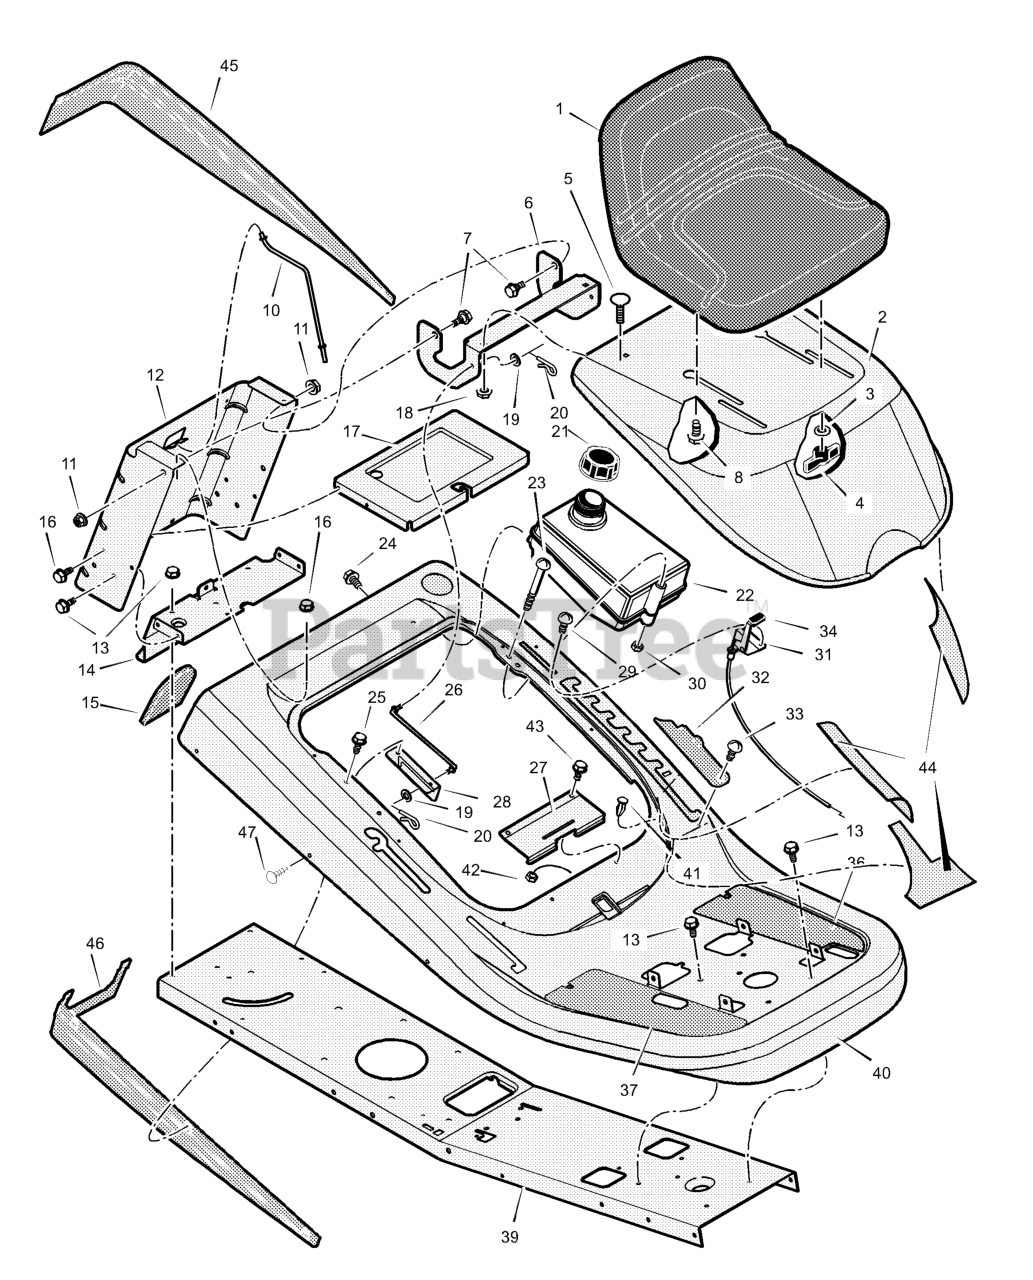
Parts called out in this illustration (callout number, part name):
3	Washer
4	Bolt, Wing
5	Bolt, Carriage
6	Bracket, Hinge
7	Bolt, Shoulder
8	Bolt, Shoulder
10	Rod, Battery
11	Nut, Flange
12	Plate, Rear
14	Plate, Hitch
17	TRAY, Battery
18	Nut, Flange
19	Washer
20	Pin, Cotter
21	Cap, Fuel Tank
22	Tank, Fuel
23	Screw
26	Rod, Hood Prop
27	Spring, Seat Deck
28	Bracket, Prop Rod
30	Nut, NY-Lock
31	Control, Throttle
32	Cover, Detent (Gray)
33	Bolt, Shoulder
36	Footmat, Left
37	Footmat, Right
41	Bumper
42	Nut
43	Screw
44	Kit, Foil Heat Shield
45	Trim, Left (Gray)
46	Trim, Right (Gray)
47	Fastener, Panel
